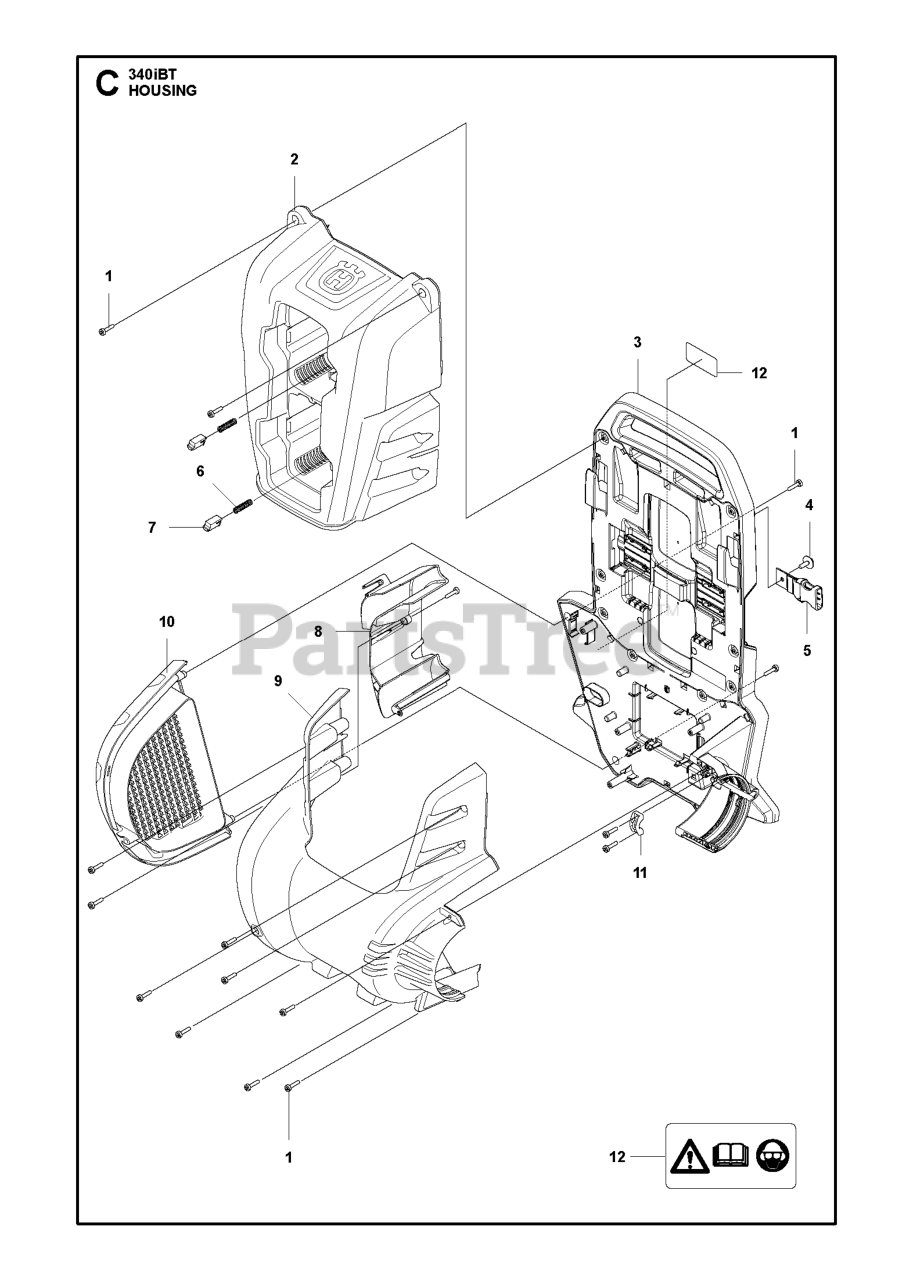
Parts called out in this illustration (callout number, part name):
1	SCREW ITXSCT PW4.2X18 10.9 ZN
4	SCREW ITXSCT MT5X16 10.9 TBO
5	STRAP BACKPLATE FEMALE
6	SPRING PUSH OUT
7	PUSH BUTTON
11	CABLE CLAMP
